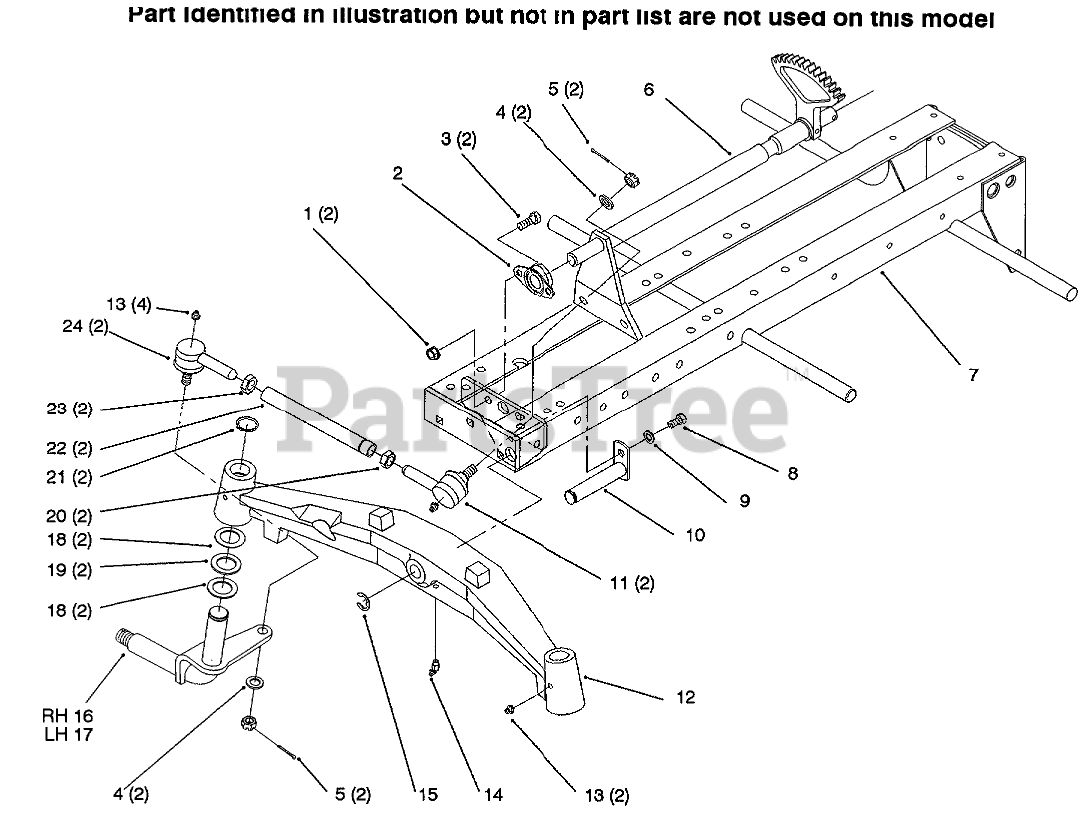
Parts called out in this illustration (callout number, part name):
1	NUT-LOCK, NI
2	BEARING-FLANGED
3	SCREW-HH
4	Spacer
5	PIN-COTTER
6	Shaft
8	SCREW-HH
9	WASHER-LOCK
10	PIN AND PLATE ASM
11	SOCKET-BALLJOINT
12	Axle-Front
13	FITTING-GREASE
14	FITTING-GREASE
15	E-RING
16	Spindle
17	Spindle
18	WASHER-THRUST
19	BEARING-THRUST
20	NUT-JAM
21	RING-RETAINING
22	Tube
23	NUT-HEX JAM 9/16-18
24	SOCKET-BALLJOINT
